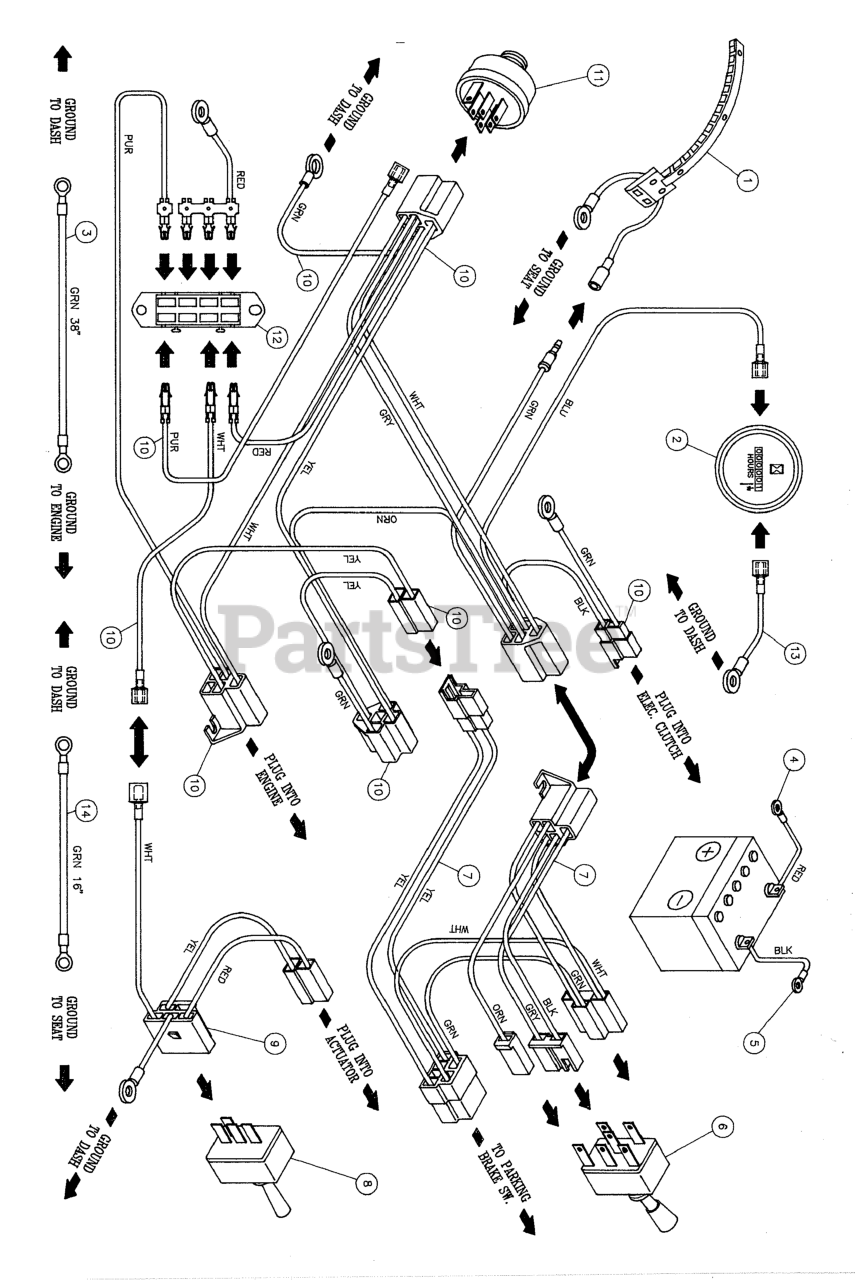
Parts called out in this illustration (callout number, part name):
1	Seat Switch Assembly
2	HOUR METER
3	Dash Panel GRD Assembly
4	POSITIVE (+) BATTERY CABLE, 22"
5	BATTERY CABLE, NEG, 22, 1/4-5/16
6	SWITCH, Electric Clutch
7	Clutch/Broke Jumper Harness
8	SWITCH, Actuator
9	Relay/Clutch Harness
10	CTR Main Harness
11	SWITCH, IGNITION, 6 POST
12	Fuse Block
13	Hour Meter GRD Assembly
14	Seat GRD Assembly
